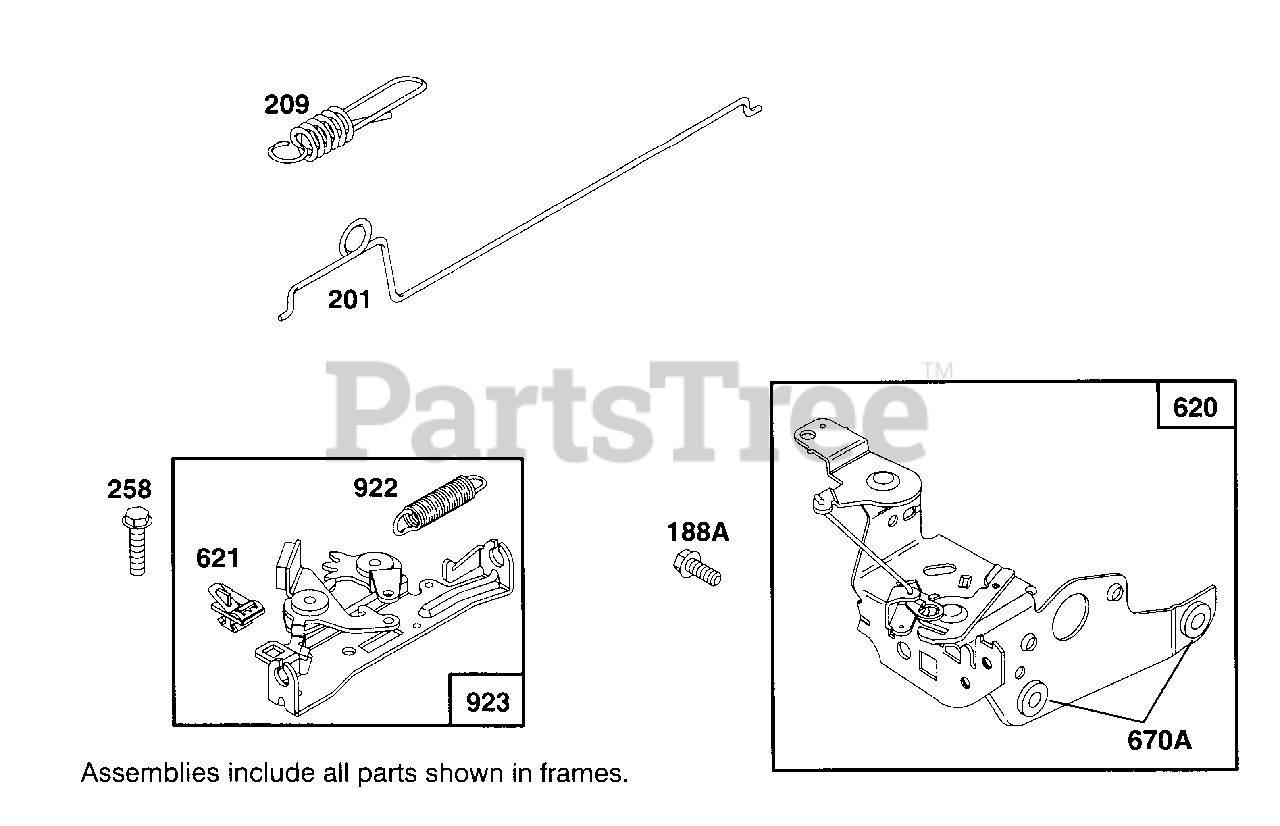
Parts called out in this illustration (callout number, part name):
188A	Screw-Hex. Head
201	Link-Governor
209	Spring-Governor
258	Screw-Hex. Head
620	Bracket-Carburetor
621	Switch-Stop
670A	Spacer-Bracket
922	Spring-Brake
923	Brake Assembly
